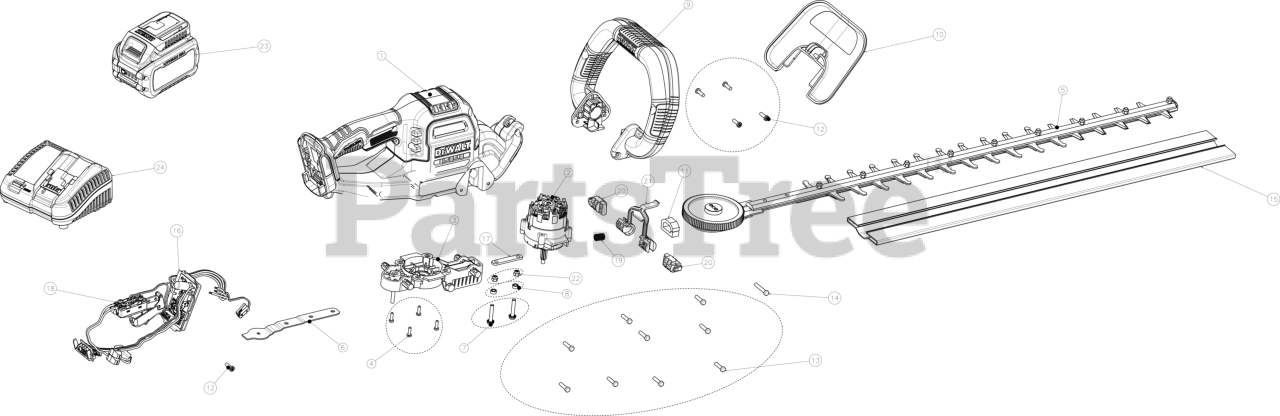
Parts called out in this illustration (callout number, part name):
1	HOUSING
3	GEARCASE ASSEMBLY
4	SCREW M6-19 T15-PLAS THD FRM
5	BLADE ASSEMBLY
6	SUPPORT PLATE
7	SCREW M5X0.8
8	SPACER BLADE
9	HANDLE AUX
12	SCREW M4.55X16 T20-PLAS THD FRM
13	SCREW M4X19 T20-PLAS THD FRM
14	SCREW MDX29 T20-PLST THD FRM
15	SHEATH BLADE
16	MODULE ASSEMBLY
17	HEDGE TRIM PLATE
18	HARNESS ASSEMBLY
19	RETURN SPRING
21	SWITCH LINK
22	NUT STOP ELASTIC M5X0.8
